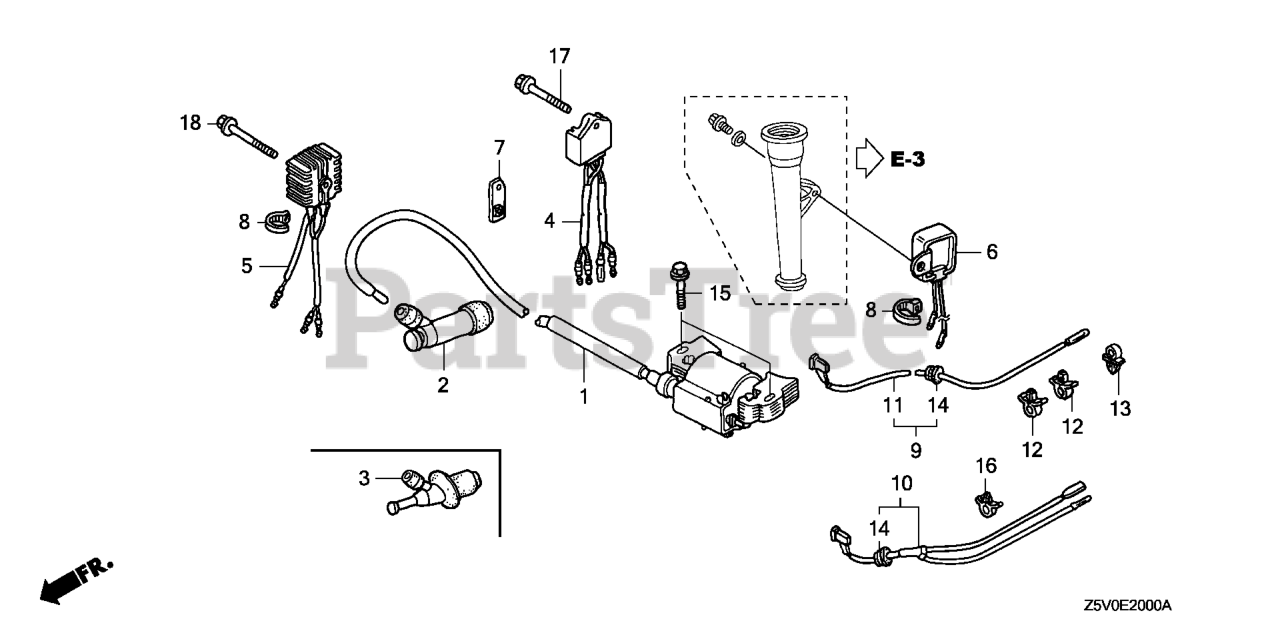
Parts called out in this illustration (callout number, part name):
1	COIL ASSY., IGNITION
2	CAP ASSY., NOISE SUPPRESSOR
4	RECTIFIER ASSY., REGULATOR
7	BRACKET, RECTIFIER
10	WIRE, STOP SWITCH
12	CLIP, BRAKE PIPE (A) (FOR NEUTRAL SWITCH)
14	GROMMET, WIRE
15	BOLT, FLANGE (6X28) (CT200) Use up to Engine SN 1530314.
17	BOLT, FLANGE (6X25)
